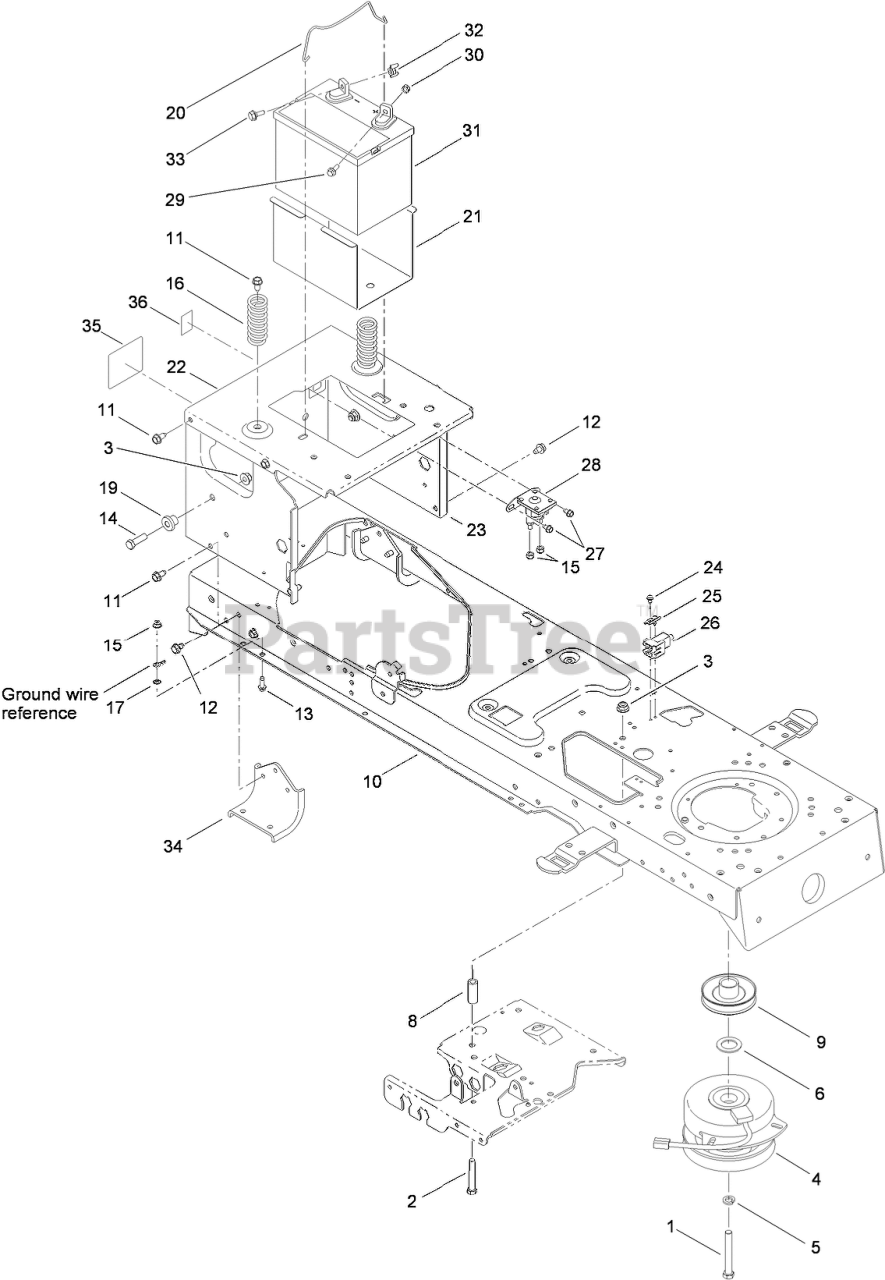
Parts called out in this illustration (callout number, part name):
1	SCREW-HH
2	SCREW-HH
3	NUT-LOCK, FLANGE
4	CLUTCH-ELECTRIC
5	WASHER-LOCK
6	WASHER-FLAT
8	SPACER
9	PULLEY-ENGINE
10	LOWER FRAME ASM
11	SCREW-TAP
12	SCREW-TAP
13	SCREW-TAP
14	SCREW-HH
15	NUT-LOCK, FLANGE
16	SPRING-COMPRESSION
17	WASHER-LOCK, EXTERNAL
19	SPACER-SHOULDER
20	ROD-HOLDDOWN, BATTERY
21	TRAY-BATTERY
22	BRACKET-FRAME, SEAT
23	FRAME-UPPER
24	SCREW-TAP
25	PLATE-SWITCH
26	SWITCH-INTERLOCK
27	SCREW-HWHTF
28	SOLENOID-12V, 2 POST 2 Tab
29	BOLT-CARRIAGE
30	NUT-SEMS
31	BATTERY-245, CCA (DRY FLAT TOP)
32	NUT-WING
33	BOLT-SHOULDER
34	BRACKET-AXLE
35	DECAL-TORO
36	DECAL-BYPASS
